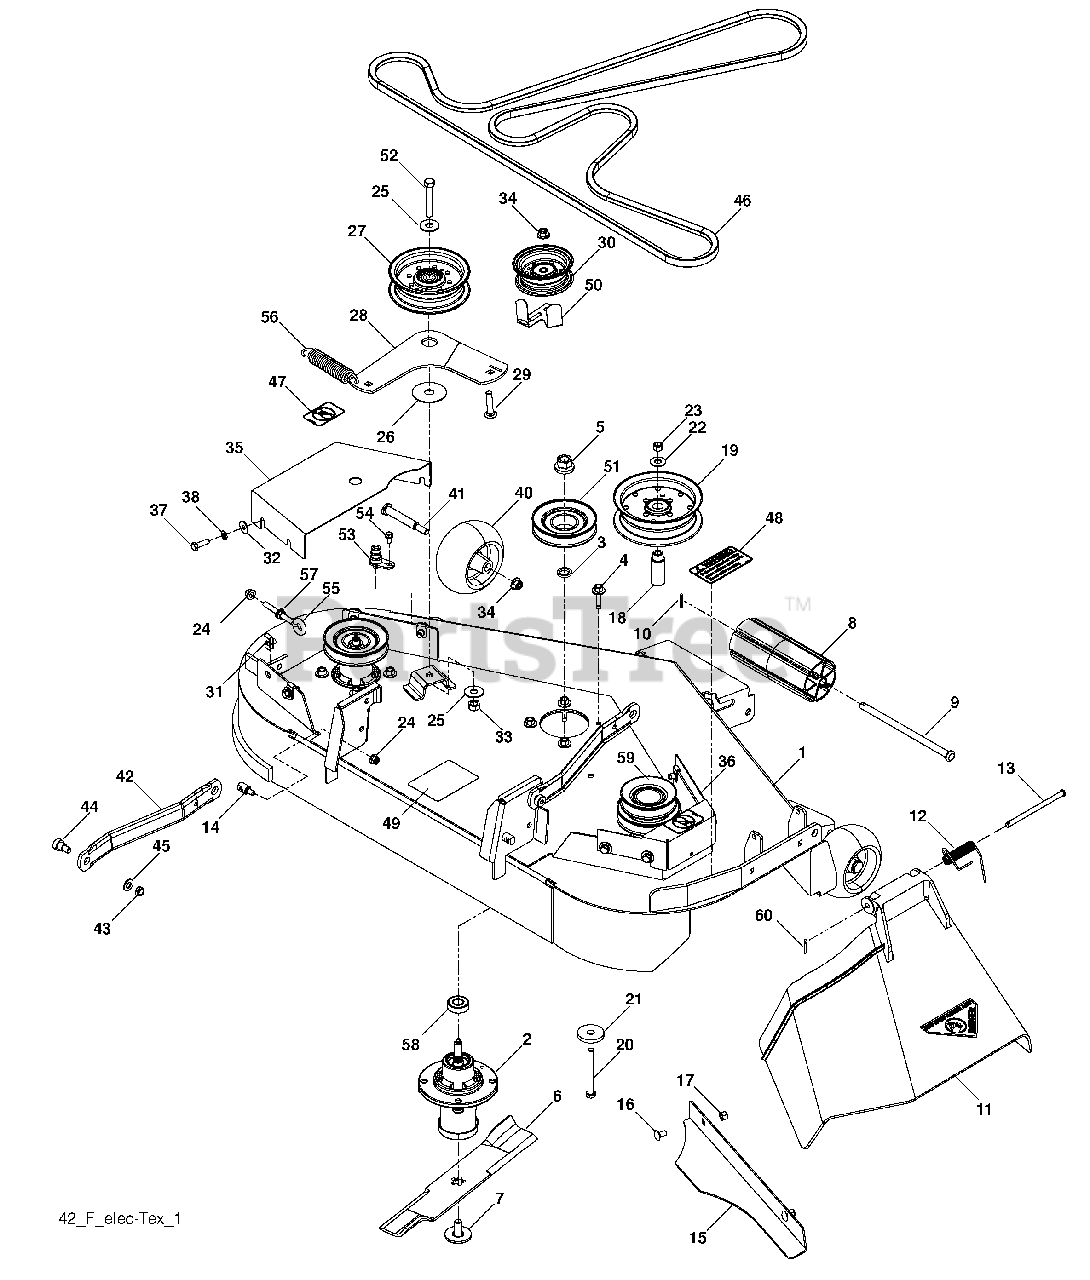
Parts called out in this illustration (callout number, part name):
1	Deck w/Decals 42"
2	Housing Assembly
3	Washer-Spacer
4	Screw, Washer Head
5	Nut, 9/16 Top Center Lock
6	Blade, 14-5/8"
7	Bolt, 7/16, Assy Blade
8	Roller, Nose
9	Rod, Roller, Nose
10	Clip Retainer
11	Discharge Chute - 42" Plastic
12	Spring - Torsion
13	Pin, Clevis 5/16 x 5.19
14	Stud, Fasten w/ Anti- Rotate
15	Confinement Plate
16	Rhsnb 5/16-18 x 5/8 Gr. 5
17	Nut 5/16-18 Hex Nyloc
18	Idler Bushing
19	Pulley, Idler
20	Hcs 3/8-16 x 3-1/2 Gr. 5
21	Heavy Washer
22	Washer, 3/8 Flat Std
23	Nut 3/8-16 Hex Nyloc
24	Nut 5/16-18 Hex Flange Nyloc
25	Washer, 7/16 Flat
26	Washer, Flat Hardened
27	Pulley, Idler Spec. Hub
28	Arm, Idler, Blk
29	Rhsnb 3/8-16 x 1-3/4 Gr. 5
30	Pulley, Idler
31	Retainer 5/16c U Type
32	Washer, 5/16 Std Flt
33	Nut, 7/16-14 Hex Nyloc
34	Nut 3/8-16 Hex Flg Nyloc
35	Shield, Belt LH
36	Shield, Belt RH
37	Hcs 5/16-18 x 1 Gr. 5
38	Wash 5/16 Slw
40	Wheel, Gauge
41	Bolt, Shoulder
42	Arm, Susp., Rear
43	Nut, 3/8-16 Hex Jam Nyloc
44	Sb 3/8-16 x 3/8 Skt Hd
45	Washer, 3/8 Sae Flt
46	Belt, 42" Fab Deck
47	Decal, No Step
48	Decal, Warning
49	Decal, Deck Sch
50	Guard, Belt
51	Pulley, Mandrel
52	Hcs 7/16-14 x 2-1/2 Gr. 5
53	Washout Port
54	Bolt, 1/4-20 x 1/2
55	Eyebolt 5/16 x 3-1/2
57	Nut 5/16-18 Hex Whizlk
58	Ball Bearing
60	Retainter Clip
